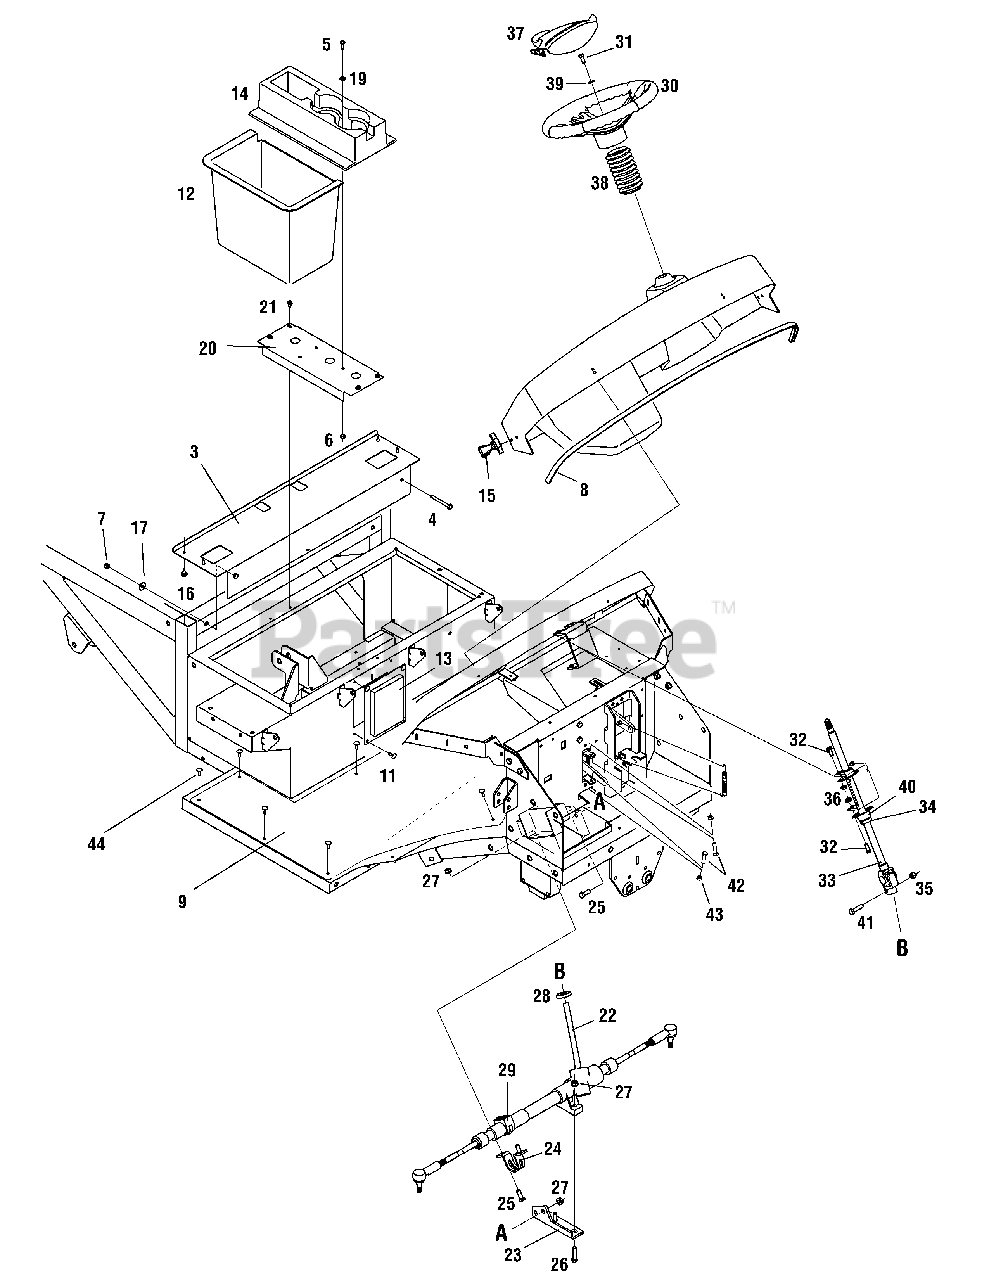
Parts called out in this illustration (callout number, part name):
2	Hood Mounting Plate
5	Hex Screw, 5/16-18 X .50
6	Hex Lock Nut, Nylon, 1/4-20
7	Hex Lock Nut, Nylon, 5/16-18
8	Trim, Bulb Seal, 1/4
10	Rivet, Pop, .3/16 x .450
11	Rivet, Pop, .188 x .37-.50
12	Container, Bulkhead
13	Panel, Shift Cover
14	Console, Cup Holder
15	Handle, Latch
16	Bumper, Rubber
17	Washer, Flat, .349 x .879 x .063
18	Washer, Flat, .194 x .62 x .063
19	Washer, Flat, .39 x 1.38 x .062
22	Gear Assembly, Steering
25	Hex Screw, 3/8-16, 1.00, Gr8
26	Hex Screw, 3/8-16, 1.50, Gr5
27	Nut, Flange Lock, 3/8-16
28	Grommet, Steering Shaft
29	Bushing, Rubber
30	Wheel, Steering
31	Hex Screw, 5/16-18, .75, Gr5, Patch
32	Hex Screw, 5/16-18, .75, Gr5
33	Shaft, Steering, 5/8 Spline
34	Collar, .75
35	Nut, Hex Lock Nylon, 3/8-16
36	Nut, Flange Lock, 5/16-18
37	Cover, Steering Wheel
38	Bellow, Steering, 4.75 Lg
39	Washer, Flat, .344 x .688 x .065
40	Bearing, Flange, .75 ID, Self-Aligning
41	Hex Screw, 3/8-16, 1.75, Gr5
42	Hex Head Screw 5/16-18 x 1.25
43	Hex Nut 5/16-18
44	Retainer Panel Clip
